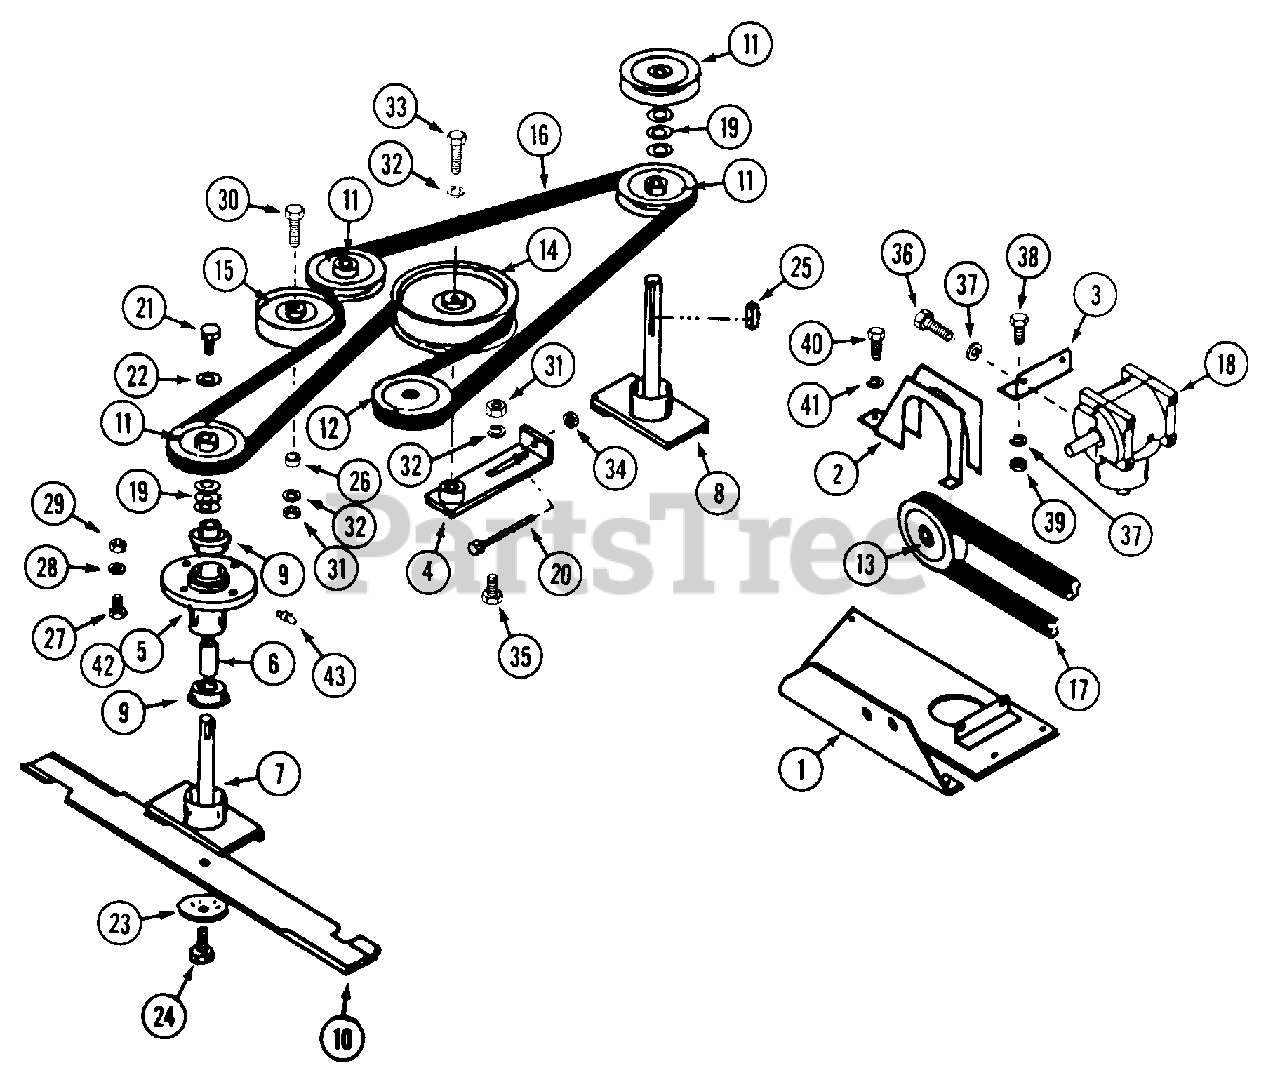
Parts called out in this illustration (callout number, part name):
1	MOUNT - gear box
2	GUARD - belt
3	ANGLE - gear box mount
4	TIGHTENER - belt
5	HOUSING - spindle
6	SPACER - spindle
7	SHAFT - spindle
8	SHAFT - spindle, long
9	BEARING - spindle
11	PULLEY - spindle
12	PULLEY - gear box output
13	PULLEY - gear box input
14	PULLEY - idler, large
15	PULLEY - idler, small
17	BELT - drive
18	GEAR BOX - angle drive
19	SPACER - washer
20	BOLT - 1/4"-20 x 4"
21	BOLT - 5/16"-24 x 3/4" lock
22	WASHER - 5/16" - 10 ga.
23	WASHER - blade
24	BOLT - 3/8"-24 x 1-1/4"
25	KEY - 3/16" x 1"
26	SPACER - idler pulley
27	BOLT - 7/16"-14 x 1-1/4"
28	LOCKWASHER - 7/16"
29	NUT - 7/16"-14
30	BOLT - 3/8"-16 x 2-1/2"
31	NUT - 3/8"
32	LOCKWASHER - 3/8"
33	BOLT - 3/8"-16 x 1-1/4"
34	NUT - 1/4"-20 lock
35	BOLT - 3/8"-16 x 1" carriage
36	BOLT - 5/16"-18 x 1"
37	LOCKWASHER - 5/16"
38	BOLT - 5/16"-18 x 3/4"
39	NUT - 5/16"-18
40	BOLT - 1/4"-20 x 1/2"
41	LOCKWASHER - 1/4"
42	HOUSING ASSEMBLY - spindle
43	FITTING - grease 1/4"-28
